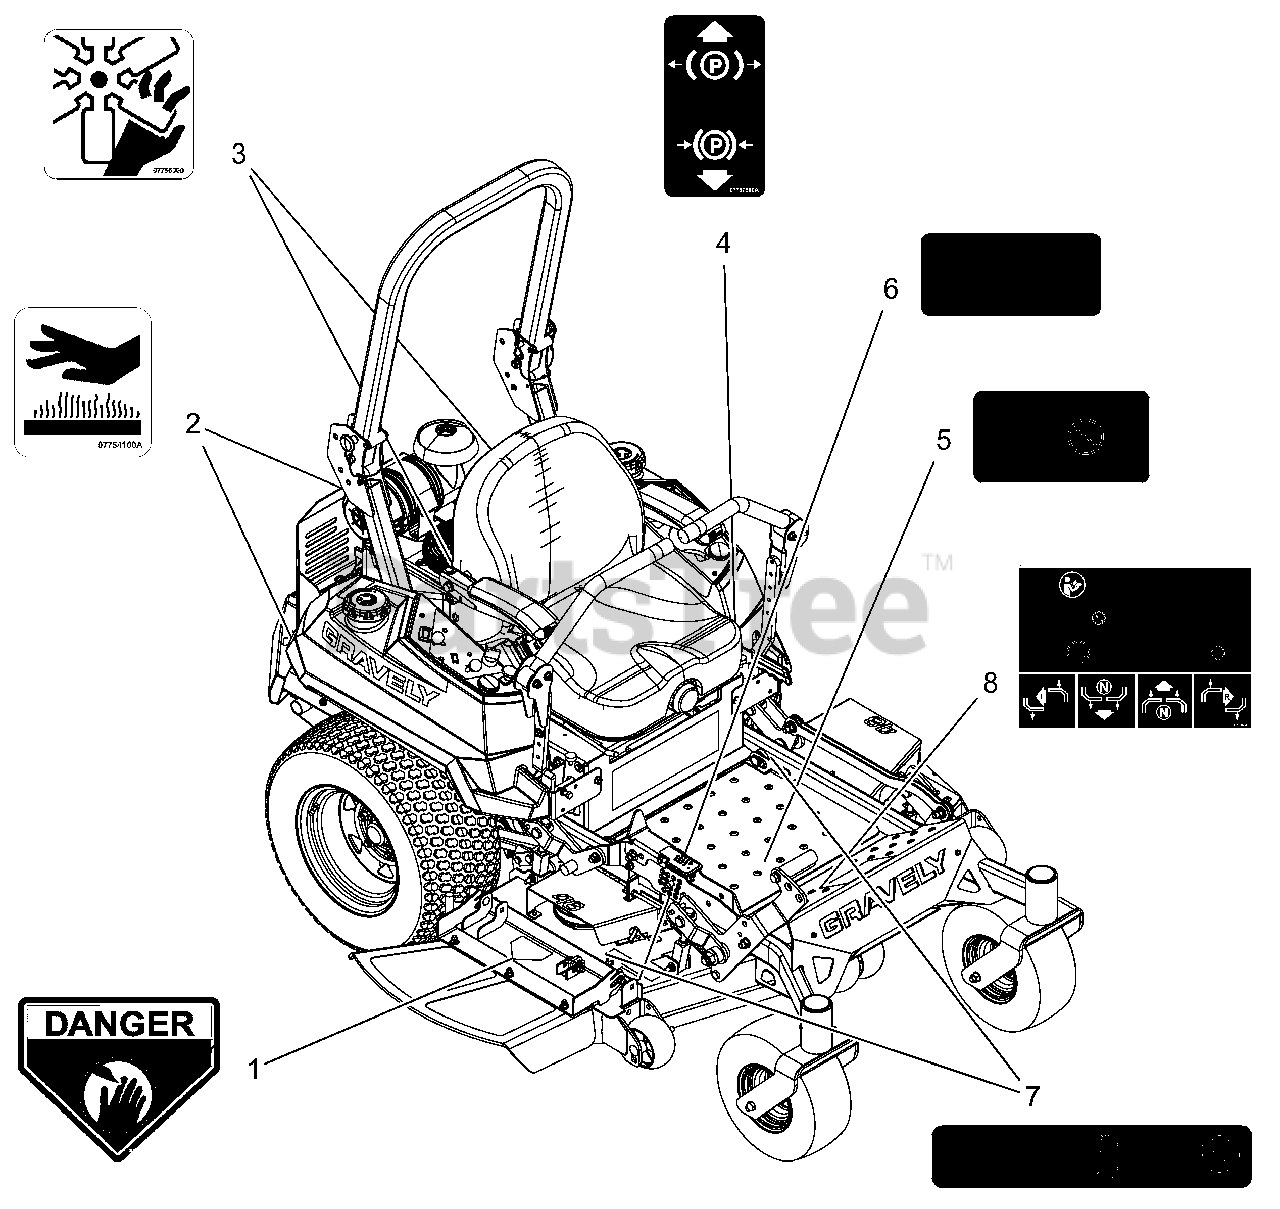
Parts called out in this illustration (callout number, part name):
1	DECAL, DANGER
2	DECAL, HOT SURFACE
3	DECAL, DANGER FAN
4	DECAL, PARKING BRAKE LEVER
5	DECAL, SAFETY - GUARDING
6	DECAL, SAFETY - DECK GUARDING
7	DECAL, DECK SAFETY
8	DECAL, INSTR SAFETY
